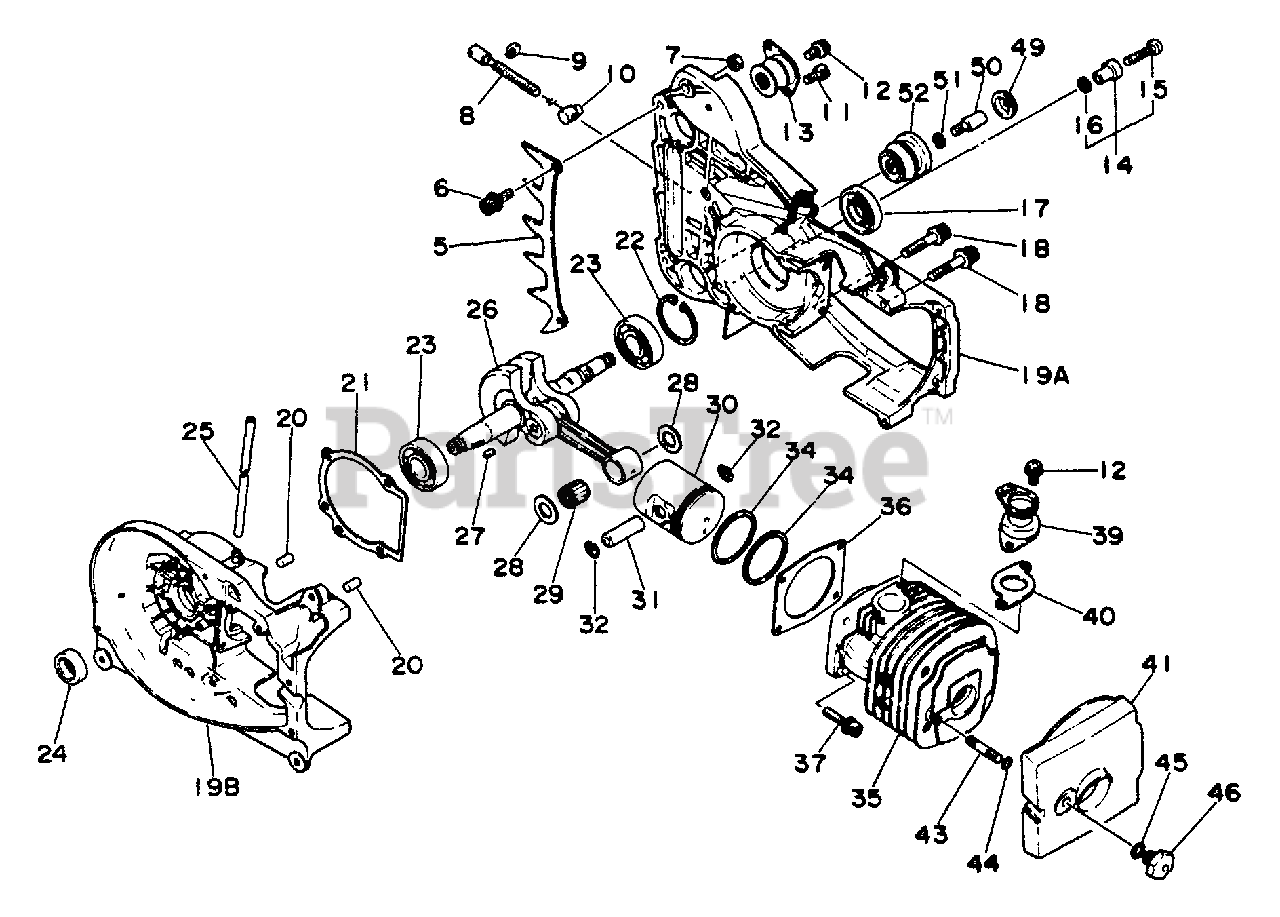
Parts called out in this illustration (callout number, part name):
5	SPIKE, BUMPER
6	BOLT 5×12
7	LOCKNUT - 5
8	SCREW, ADJUSTER
10	TENSIONER, CHAIN
11	BOLT 4×10
12	SCREW 5×10
13	CUSHION
14	CHAIN CATCHER KIT
15	SCREW 5×25
16	WASHER, FLAT 5.5×10×0.8
17	SEAL, OIL 18
18	BOLT M5×35
19	CRANKCASE KIT
19A	CRANKCASE KIT
19B	CRANKCASE KIT
20	PIN, LOCATING 5×10
21	GASKET
22	RING, SNAP 35
23	BEARING, BALL 6202
24	SEAL, OIL
25	PIPE, IMPULSE 3×6×75
26	CRANKSHAFT ASSY
27	KEY, WOODRUFF
28	WASHER, THRUST
29	BEARING, NEEDLE
30	PISTON
31	PIN, PISTON
32	RING, SNAP
34	RING, PISTON
35	CYLINDER
36	GASKET, CYLINDER
37	BOLT 5×20
39	ADAPTOR, INTAKE
40	GASKET, INTAKE
41	COVER, CYLINDER
45	O-RING 12 MM
46	NUT
49	CAP, CUSHION
51	WASHER, SPRING 5
52	CUSHION
